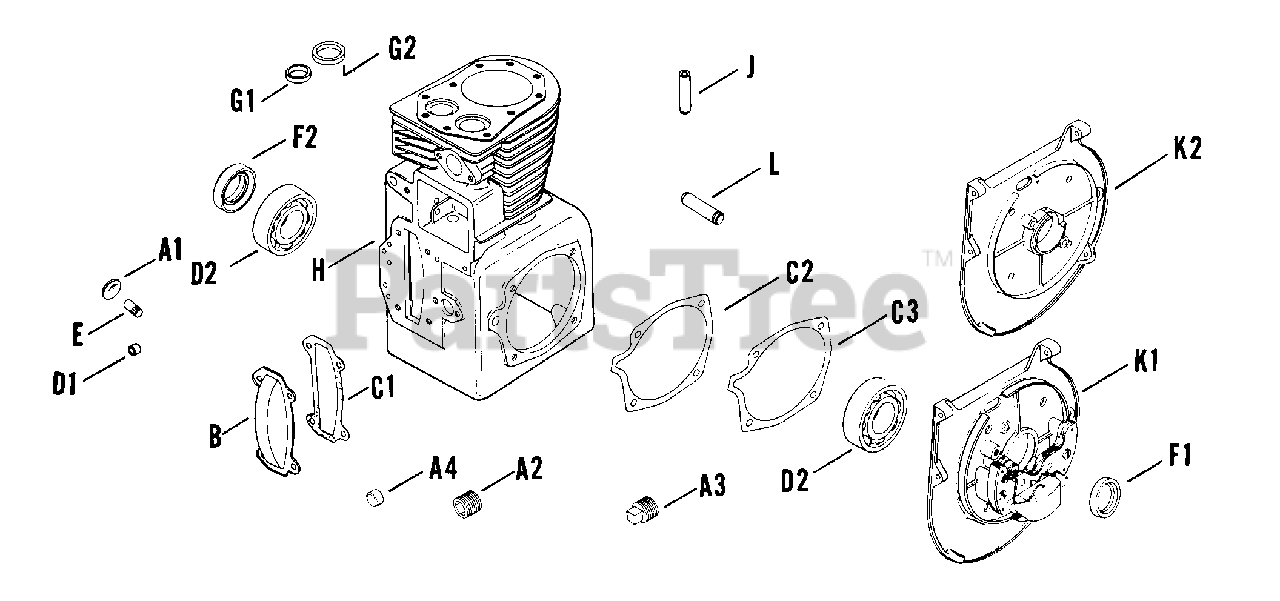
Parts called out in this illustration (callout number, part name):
A1	PLUG, WELCH EXPANSION
B	COVER, CAMSHAFT - DISCONTINUED
C1	GASKET, CAMSHAFT COVER
C2	GASKET, BEARING PLATE
C3	GASKET, BEARING PLATE
D1	BEARING
D2	BEARING, BALL
E	SHAFT, GOVERNOR GEAR
F1	SEAL - USE 47 032 06
F2	SEAL - USE 47 032 07
G1	INSERT - DISCONTINUED
J	GUIDE, VALVE - DISCONTINUED
